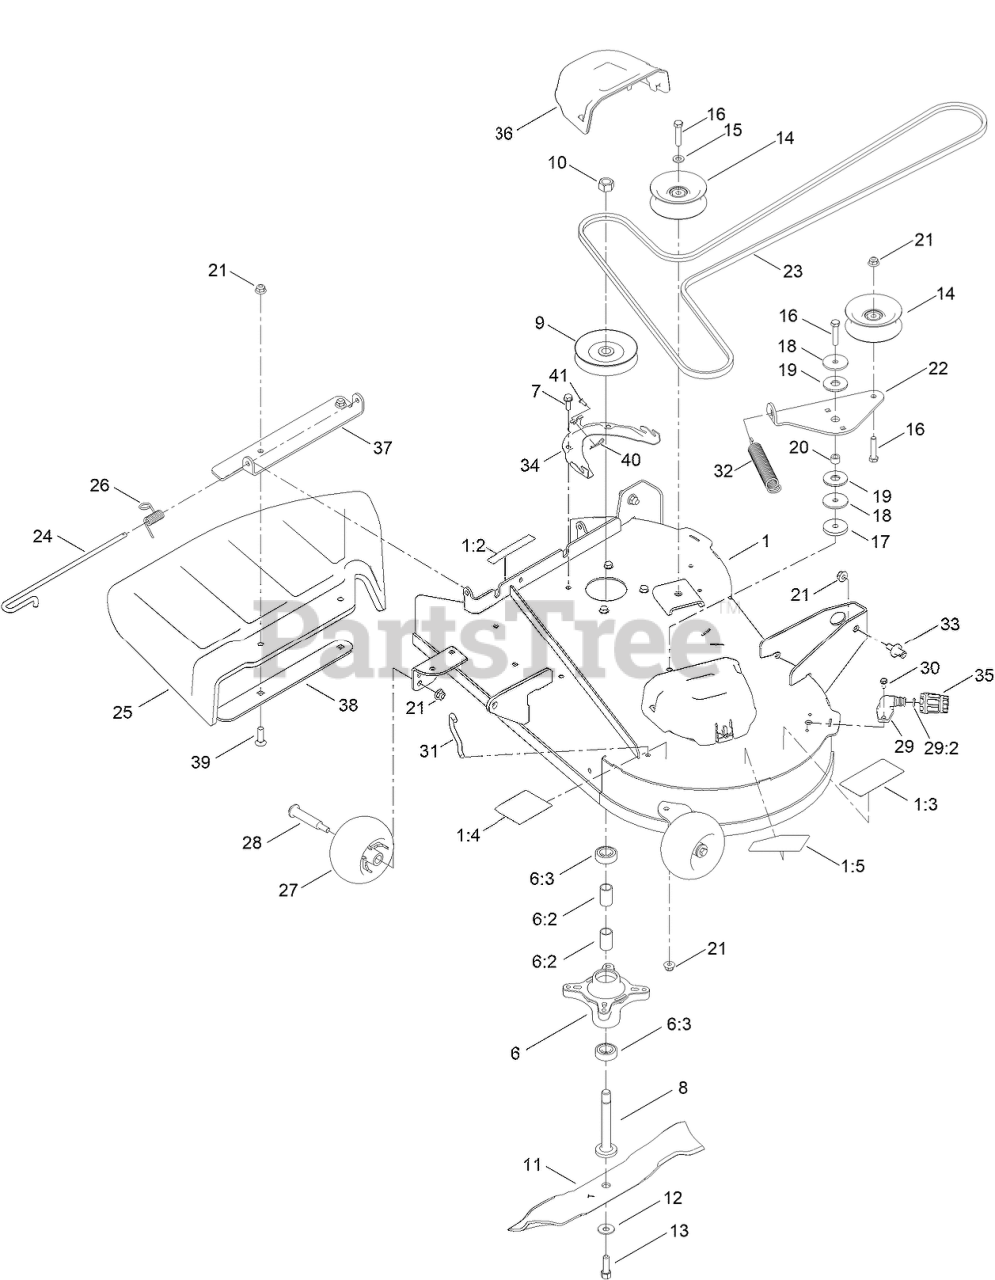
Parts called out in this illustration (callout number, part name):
1	34 INCH DECK AND DECAL ASM
1:2	DECAL-DANGER
1:3	DECAL-DANGER, DECK
1:4	DECAL-ROUTING, BELT
1:5	DECAL-DECK
6	SPINDLE ASM
6:2	SPACER
6:3	BEARING-BALL
7	SCREW-TAPTITE
8	SHAFT-SPINDLE
9	PULLEY ASM
10	NUT-HEX
11	BLADE 17.50 [BLACK]
12	WASHER-BELLEVILLE
13	SCREW-HH
14	PULLEY-IDLER, FLAT
15	WASHER-FLAT
16	SCREW-HH
17	WASHER-PLAIN
18	WASHER-REBOUND
19	WASHER-FRICTION, COMPOSITE
20	SPACER
21	NUT-HF, NI
22	ARM-IDLER
23	BELT-V
24	PIN-CHUTE
25	DEFLECTOR-RUBBER
26	SPRING-TORSION
27	ROLLER-SCALP, ANTI
28	BOLT-SHOULDER
29	FITTING-WASHOUT
29:2	O-RING
30	SCREW-HWH
31	HOOK-RETURN SPRING
32	SPRING-EXTENSION
33	PIN-DECK
34	BRACKET-COVER, BELT
35	CONNECTOR-HOSE
36	COVER-BELT
37	BRACKET-DEFLECTOR, TOP
38	PLATE-DEFLECTOR, BOTTOM
39	SCREW-CARR
40	PIN-HAIR
41	SCREW
